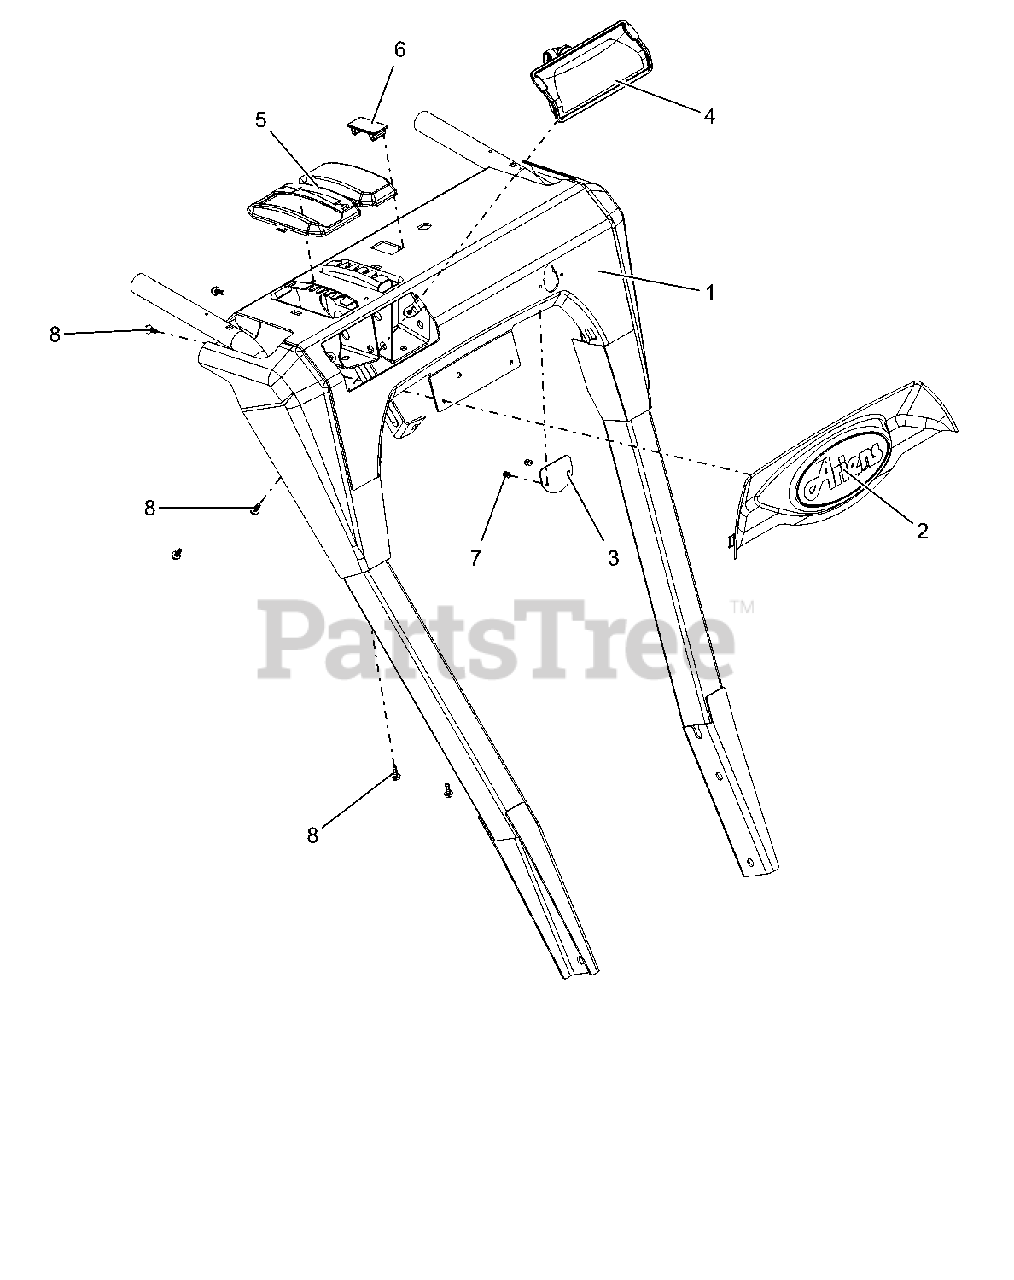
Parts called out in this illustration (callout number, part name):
1	PANEL, DASH - W/CTR DECAL
2	BEZEL, DASH-ARIENS LG DASH
3	COVER, DASH BRKT, BRUSH
4	HEADLIGHT ASY, HOLO 15W 2 SHOT
5	BEZEL, SHIFT - FRICTION BRUSH
6	PLUG,DASH PANEL
7	RVT-POP #43 .125X.313 STL ZINC
8	SCR-TAP #10X.50 BOSS INDHXHD
